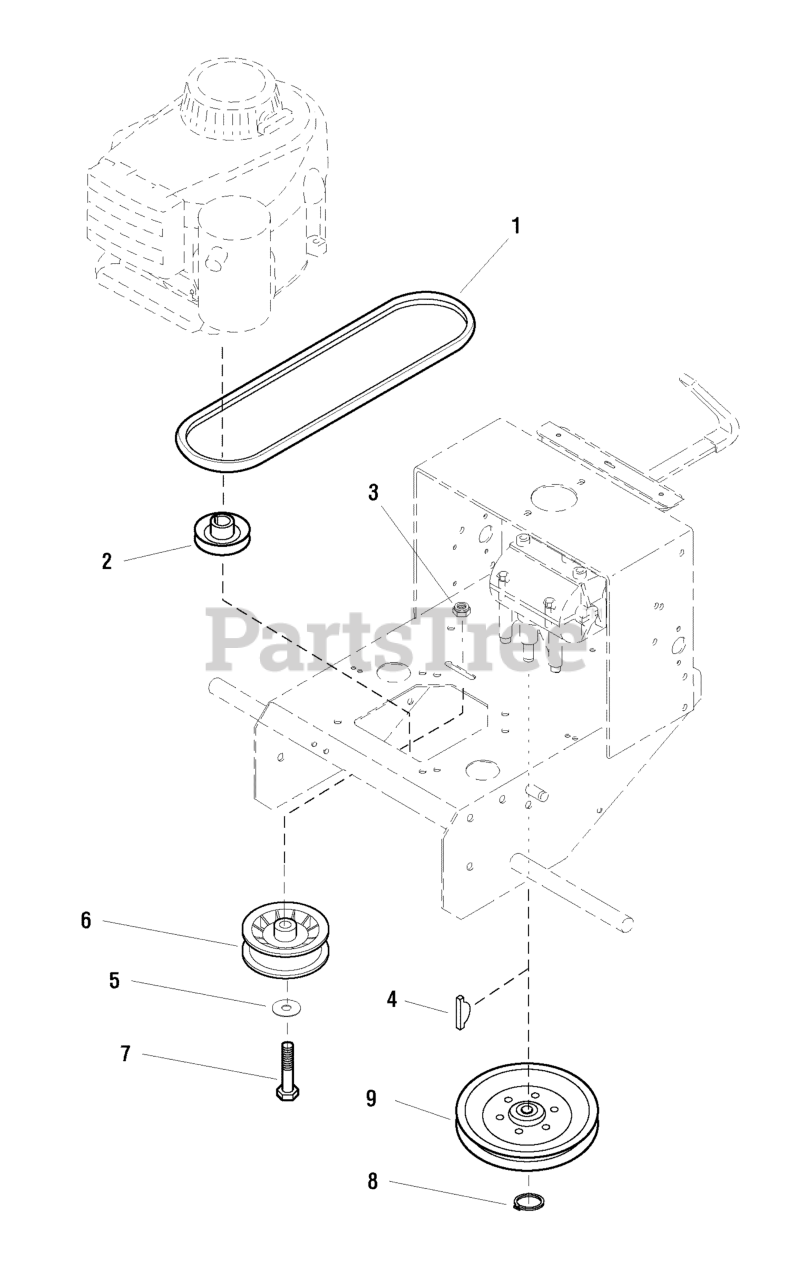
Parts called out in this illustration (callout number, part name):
2	PULLEY, Transmission Drive
3	NUT, 3/8-16 Hex Nylon Flange
5	WASHER, 3/8 SAE
6	IDLER PULLEY ASSEMBLY
7	BOLT, 3/8-16 X 1-3/4" GD5 CZ
8	RING, External, Snap
9	PULLEY, Gear Box Input
